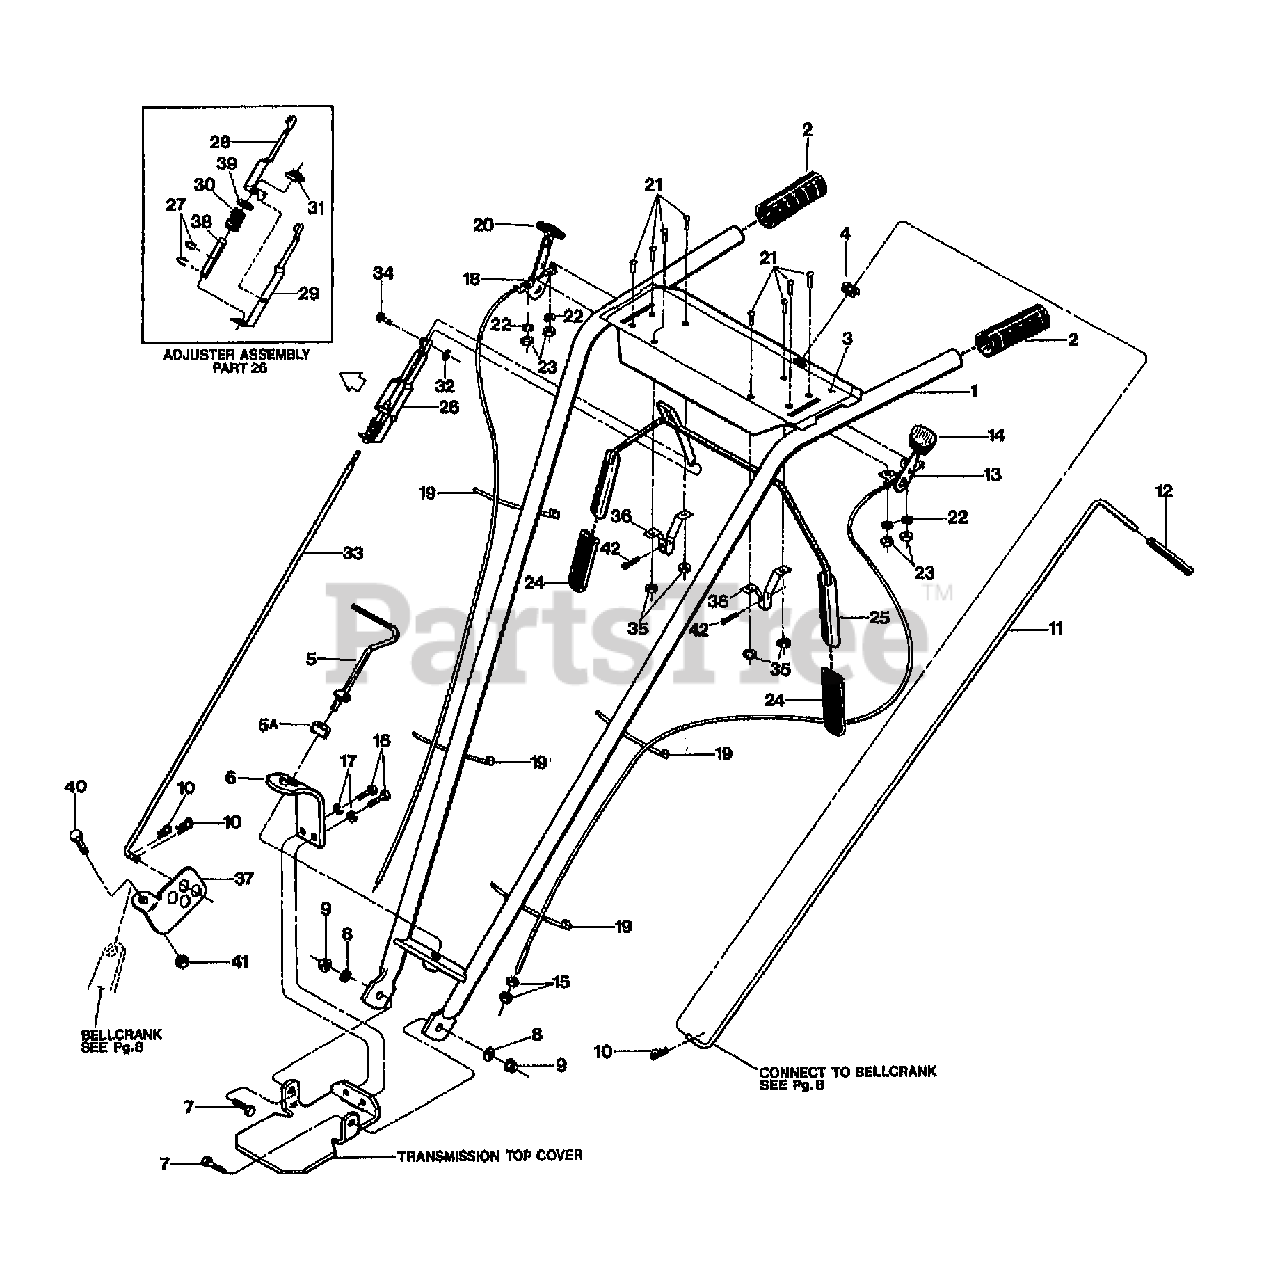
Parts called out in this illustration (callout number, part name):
1	ASSM-HANDLEBAR W/GRIPS (INCL. 2-5A)
2	GRIP-H/BAR SMOOTH
3	DECAL-CONTROL PANEL
4	BUSHING-NYLON
5	ASSM-STUD H/B
5A	WASHER-1.0X.38X.375
6	PLATE-HANDLEBAR ADJUST
7	SCR-HH 3/8-16X1.0 G5 ZP
8	WASHER-FLAT 3/8 SAE
9	NUT-LOCK 3/8-16 NYLON ZP
10	PIN-CLIP .08
11	ROD-REV W/GRIP OPC - COMPLETE (INCL. GRIP #9198)
12	GRIP-CONTROL ROD
13	CABLE-WHEEL CLUTCH OPC (INCL. 14,15,19,21-23)
14	KNOB-WHEEL DRIVE CABLE
15	NUT-HEX 5/16-24
16	SCR-HH 3/8-16X.75 G5 ZP
17	WASHER-LK .375 @ DEPL
18	CABLE-THROTTLE ECONO OPC (INCL. #20)
19	TIE-RED (PLASTIC)
20	KNOB-THROTTLE CABLE
21	SCR-RH M10-32X.5 MACH
22	WASHER-LK M10
23	NUT-HH M10-32X.125
24	GRIP-PADDLE SM FRAME OPC
25	BAIL W/GRIPS OPC (INCL. TWO GRIPS, #24)
26	ASSM-ADJUSTMENT OPC (INCL. 27-30,38-39)
27	RING-KLIP .500 ZINC
28	ADJUSTER-RT SIDE OPC
29	ADJUSTER-LT SIDE OPC
30	SPRING-ADJUSTER OPC
31	WELDNUT 5/16-18
32	RING-KLIP .188 DIA
33	ROD-CONTROL OPC
34	ASSM-PIN & CLIP (SMALL FRAME)
35	NUT W/LKWASHER #10-32 ZP
36	BRACKET-BAIL OPC
37	SWIVEL-SMALL FRAME
38	BUSHING-.5X.334X2.88
39	WASHER-.75X.51X.06 ZP
40	SCR-HH 1/4-20X.75 G5 ZP
41	NUT-LK 1/4-20
42	SCR-HWH 1/4-20 X .5 STH
